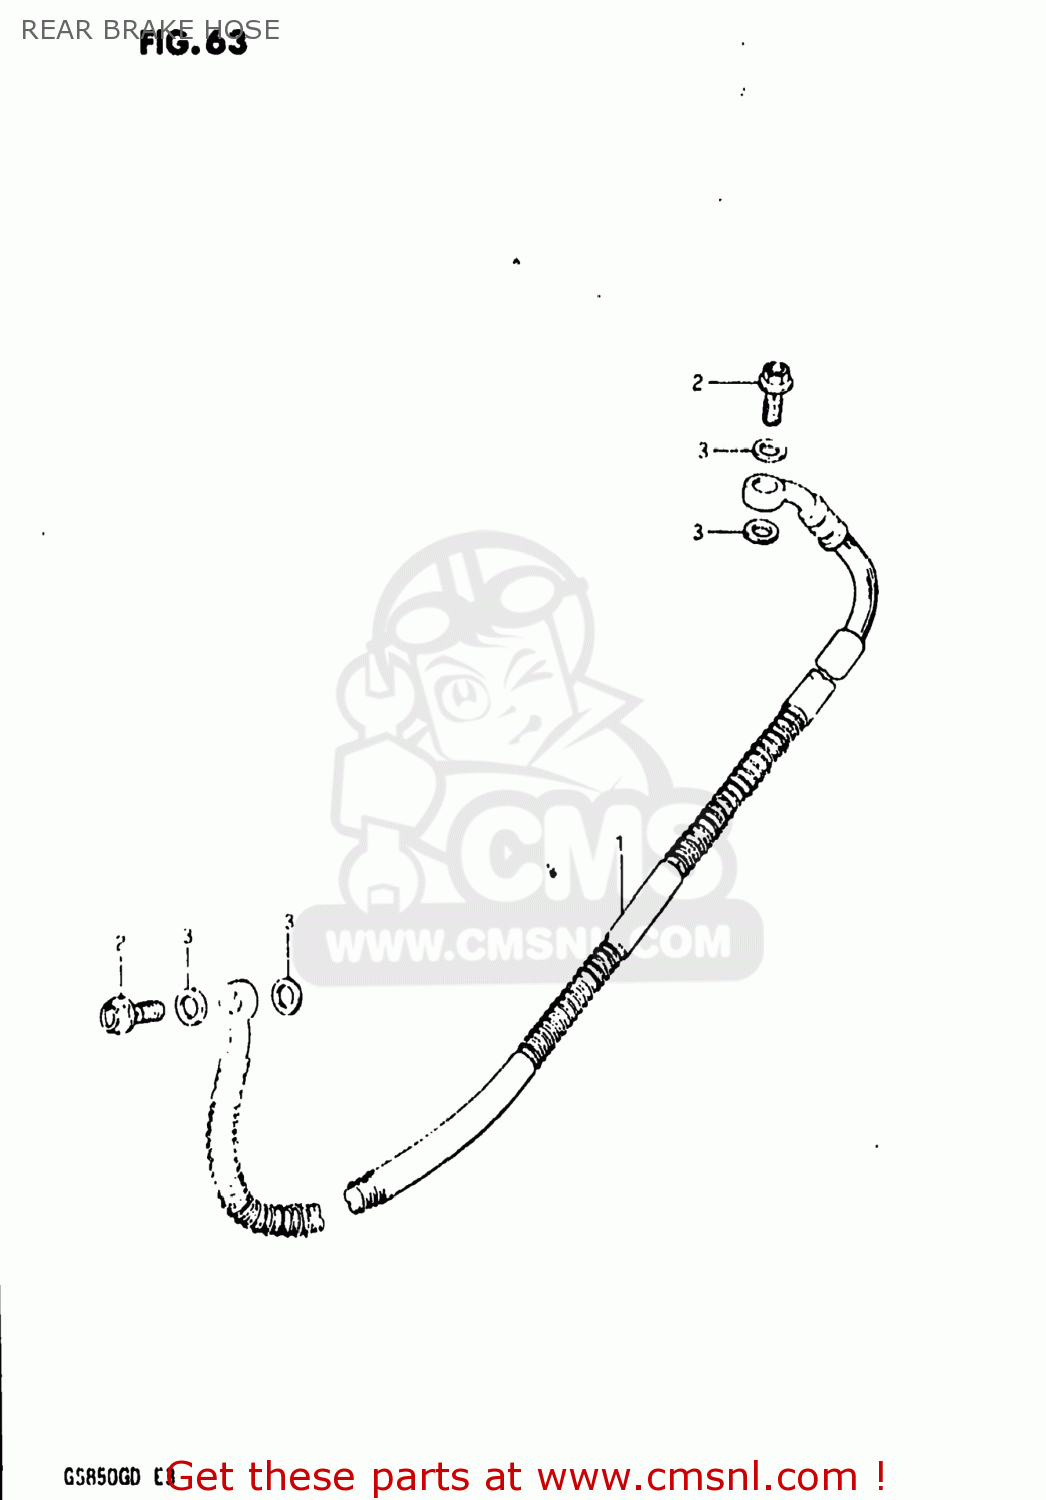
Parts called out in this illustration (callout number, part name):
1	HOSE,REAR BRAKE
2	BOLT,UNION
3	WASHER
